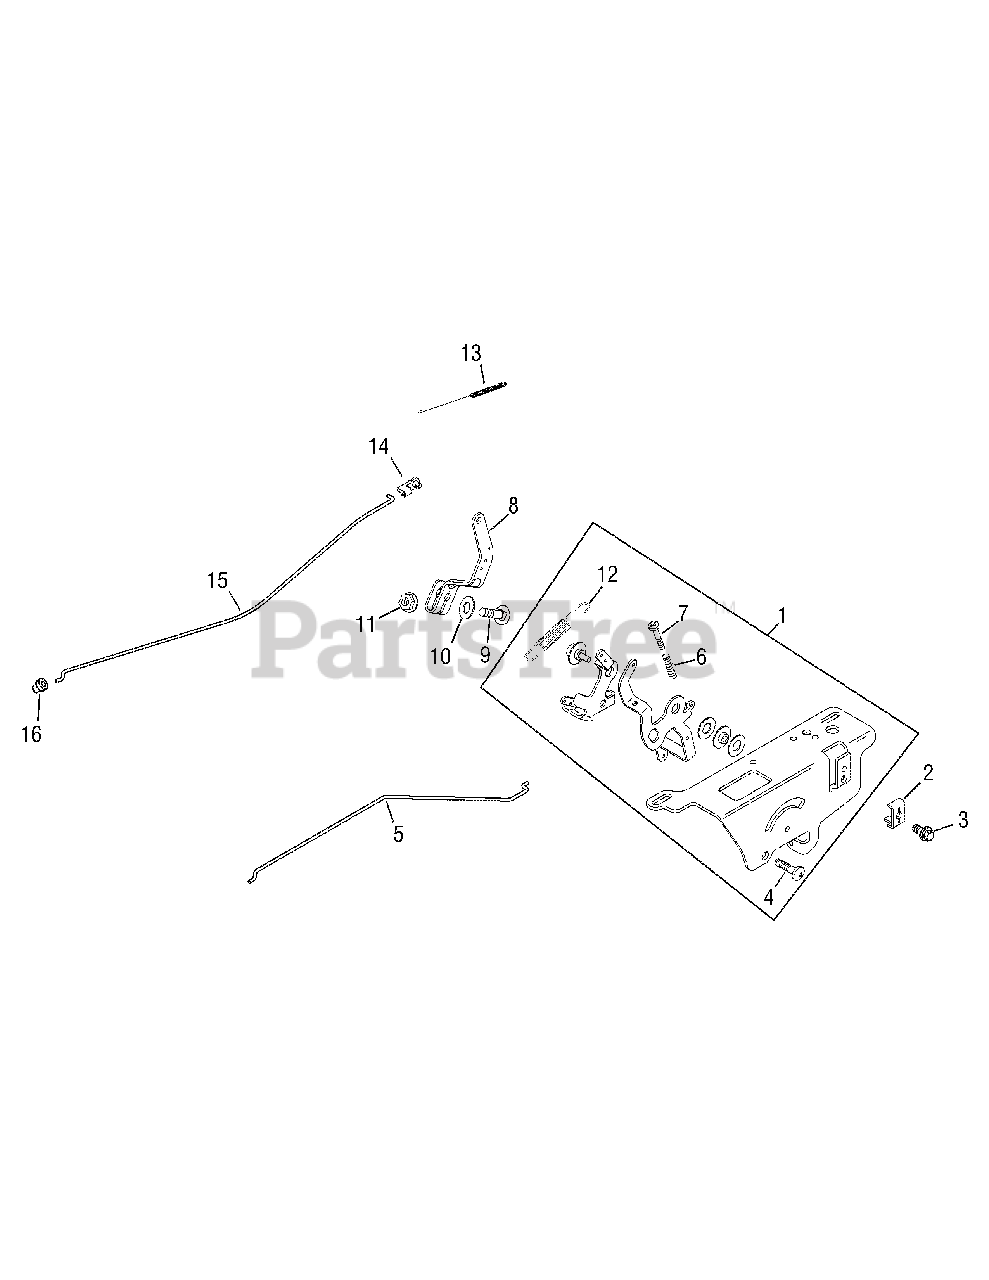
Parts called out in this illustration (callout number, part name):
1	Control Assembly, Speed
2	Clamp, cable
3	Screw, hex fl ange thread forming M5 x 0.8 x 16
4	Screw, 6 lobed socket thread forming M6 x 1.0 x 20
5	Linkage, choke
6	Spring, speed control
7	Screw, hex fl ange thread forming M4 x 0.7 x 25
8	Lever, governor
9	Bolt, round head square neck 1/4-20 x 1"
10	Washer, internal tooth lock 1/4"
11	Nut, hex. fl ange 1/4-20"
12	Spring, governor
13	Spring, linkage
14	Bushing, throttle linkage
15	Linkage, throttle
16	Bushing, linkage retaining
